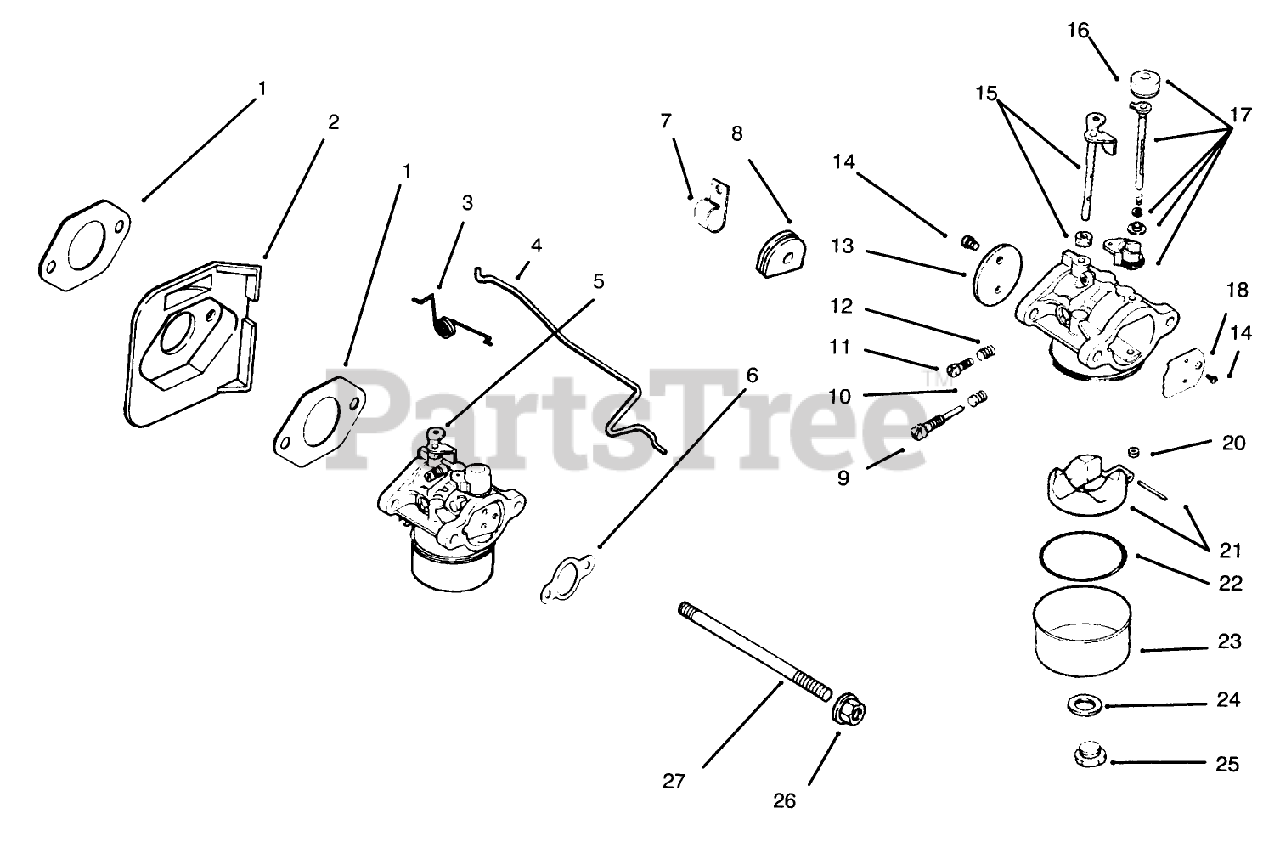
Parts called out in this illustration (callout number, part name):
1	Gasket-Carburetor
2	Deflector-Heat
3	Spring Choke
4	Linkage Choke
5	Carburetor Assembly (Incl Ref. #9-25)
6	Gasket-Air Cleaner
7	Clamp
8	Grommet
9	Needle-Idle
10	Spring-Idle
11	Screw-Idle
12	Spring-Idle
13	Plate-Choke
14	Screw
15	Shaft-w/Lever & Seal
16	Cap-Choke Lever
17	Kit-Choke Repair (Incl. Ref.#16)
18	Plate-Choke
20	Jet-Main
21	Kit-Float
22	Gasket-Bowl
23	Bowl-Fuel
24	Gasket-Bowl
25	Screw-Bowl
26	Nut
27	Stud
